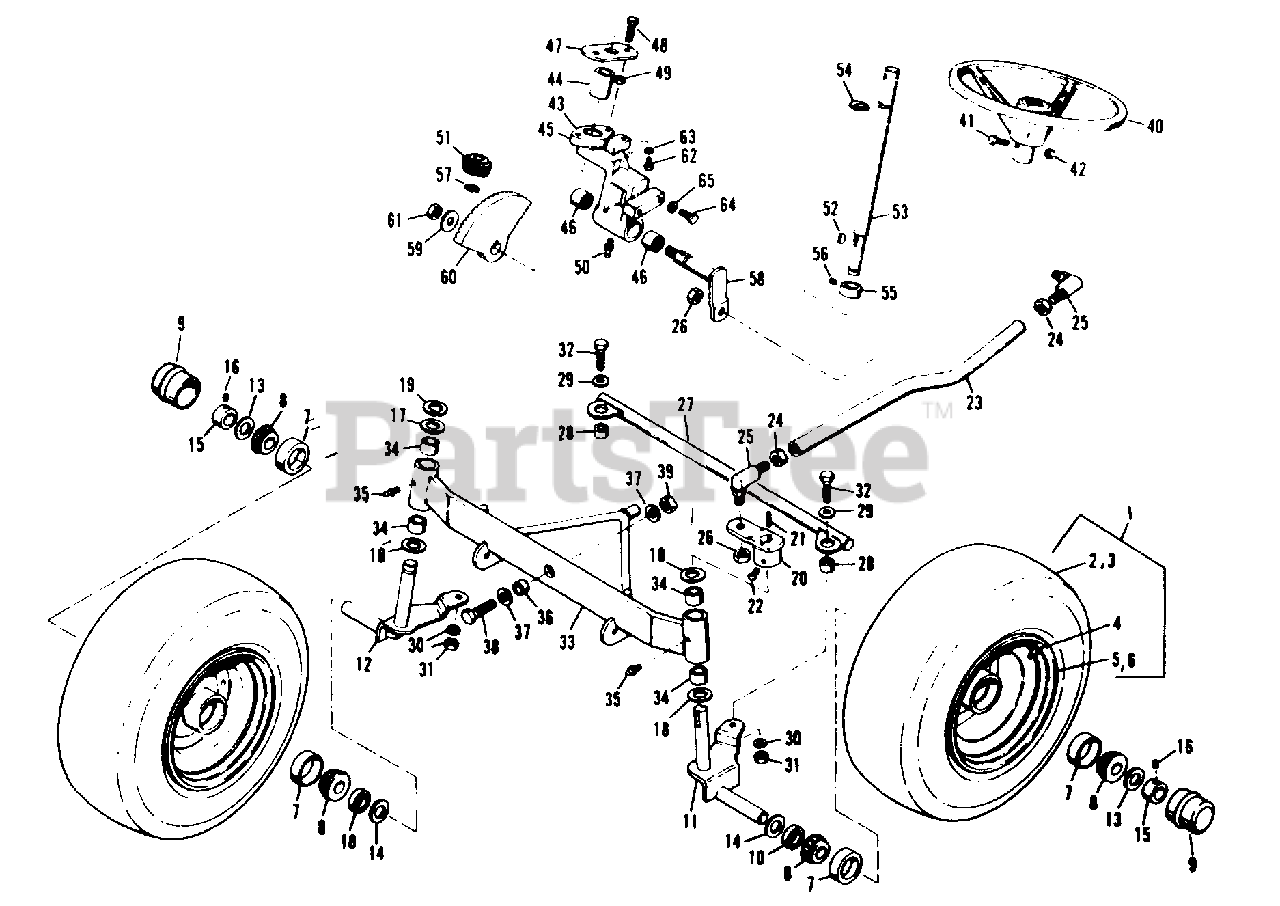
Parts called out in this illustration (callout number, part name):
1	Wheel & Tire Assy.
4	Valve Stem & Cap
5	Wheel-Sub Assy.
6	Wheel (Front)
7	Bearing, Cup
8	Bearing, Cone (Without Seal)
9	Hub Cap
11	Spindle Assy. L.H.
12	Spindle Assy. R.H.
15	Collar, Set
16	Cup Pt. Socket Head Set Screw 5/16"-18 N.C. x 5/16"
17	Washer (Use Beneath Snap Ring)
19	Ring, Retaining
20	Arm Assy., Strg. L.H.
22	Cup Pt. Socket Head Set Screw, 5/16"-18 N.C. x 1/2"
24	Hex Nut, Jam, 1/2"-20 N.F.
25	Joint, Ball
26	Hex Nut, Jam Lock, 1/2" 20 N. F.
27	Link Assy., Drag
29	Washer, Plain, 3/8"
30	Lock Washer, 3/8"
31	Hex Nut, Full, 3/8"-16 N.C.
32	Hex Cap Screw, 3/8"-16 N.C. x 1-1/4"
33	Axle Assy., Front
35	Fitting, Grease
37	Plain Washer, 1/2"
38	Hex Cap Screw, 1/2"-13 N.C. x 1-3/4", Grade 5
39	Hex Nut, Full Lock, 1/2"- 13 N.C.
40	Steering Wheel
41	Hex Head Screw, 5/16"-18 N.C. x 1-1/4"
42	Hex Nut, Lock 5/16"-18 N.C.
43	Steering Bracket, Casting
44	Bushing, Steering
45	Casting and Bearing
46	Bearing, Needle
47	Plate, Steering
48	Hex Cap Screw, 3/8"-16 x 1-1/4"
49	Hex Jam Nut, 3/8"-16
50	Fitting, Grease
51	Pinion, 15T, Bevel
52	Key, Woodruff, No. 6 5/32" W. x 5/8" Dia.
53	Shaft, Steering
54	Ring, Retaining
55	Collar, Set
56	Set Screw, 5/16"-18 N.C. x 1/4"
57	Ring, Retaining
58	Arm Assy. Steering
59	Plain Washer, 7/16"
60	Gear, 23T, Bevel
61	Hex Nut, Lock, 7/16"- 14 N.C.
62	Hex Cap Screw, 3/8"-16 N.C. x 3/4"
63	Lock Washer, 3/8"
64	Hex Cap Screw, 3/8"-16 N.C. x 7/8"
65	Lock Washer, 3/8"
